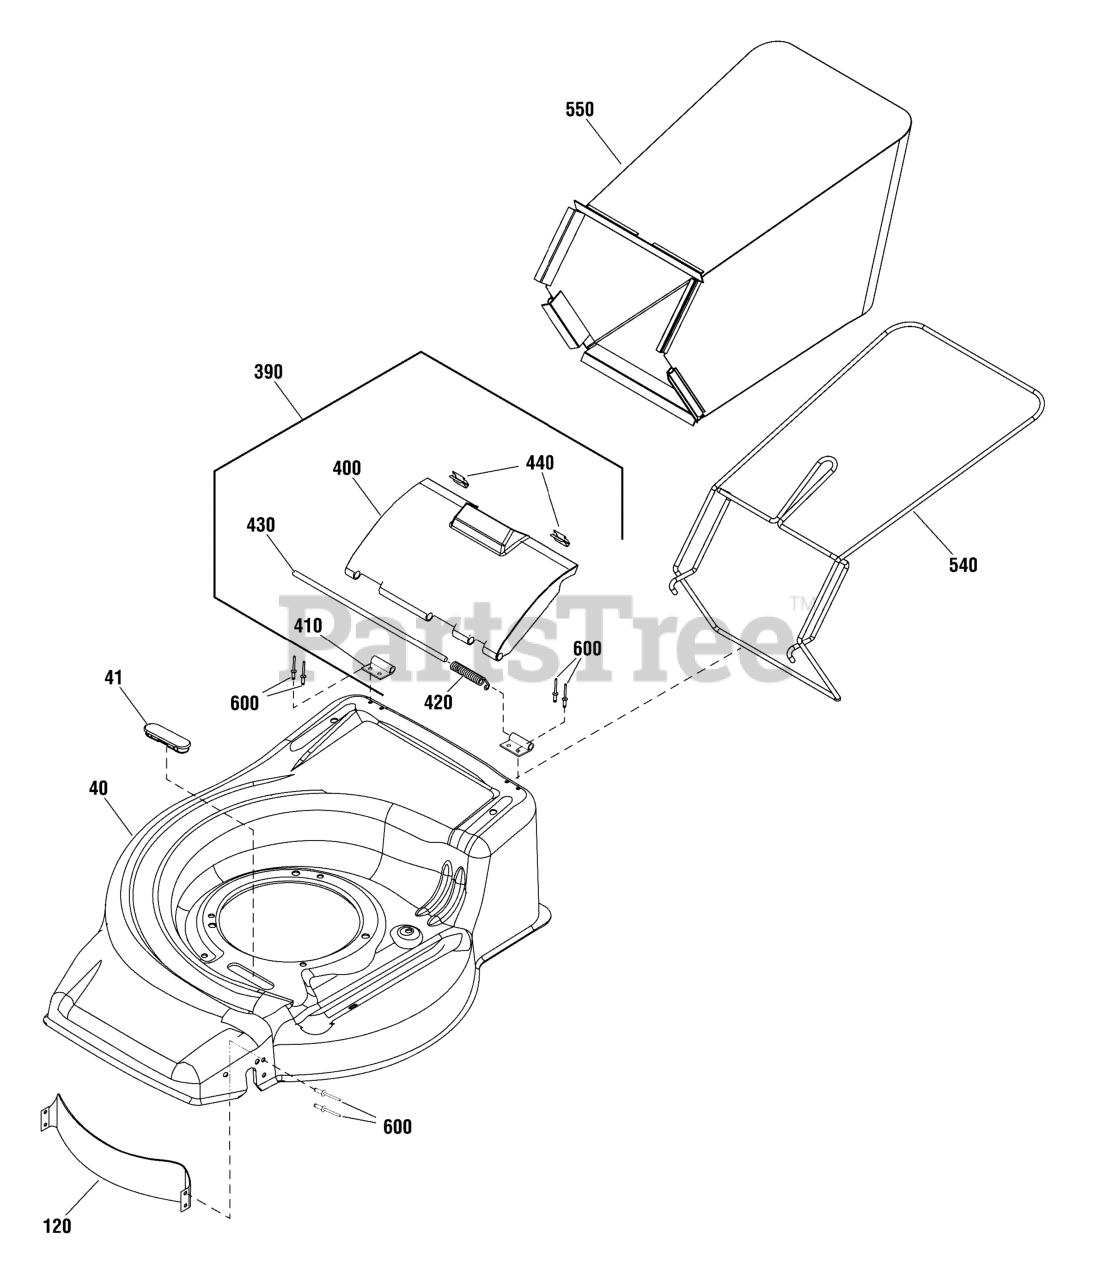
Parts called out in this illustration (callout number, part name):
40	* BASEPLATE, Red
40	BASEPLATE, Brunswick Green
41	PLUG, Muffler Slot
120	FRONT SKIRT
390	REAR FLAP ASSEMBLY
400	FLAP, Rear
410	BRACKET, Flap
420	SPRING, Flap
430	PIVOT ROD
540	FRAME, Catcher
550	BAG, Catcher
600	RIVET
